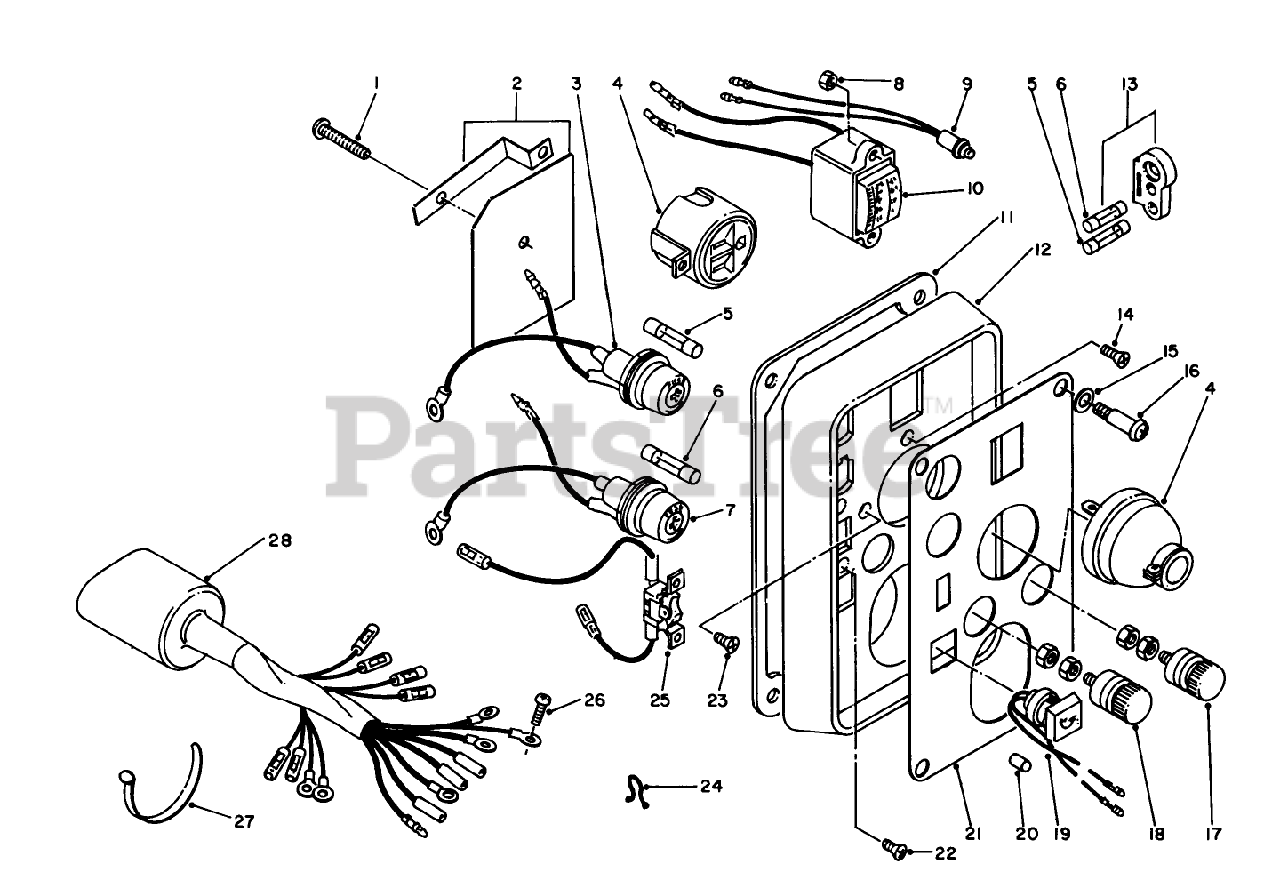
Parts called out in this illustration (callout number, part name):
1	Screw
2	Insulator-Panel Back
3	Holder-Fuse
4	Receptacle
5	Fuse (5A)
6	Fuse (10A)
7	FUSE HOLDER ASM
9	CYCLE METER LAMP ASM
10	Hertz Meter
11	Cushion Panel
12	Panel-Control
13	Fuse Set-Spare
14	Screw
15	Washer
16	Screw
17	TERMINAL +
18	Terminal (-)
19	Lamp-Oil Level
21	Plate-Panel
22	Screw
23	Screw
24	Clamp
25	Switch
26	Screw
27	Clamp
28	Harness-Control
